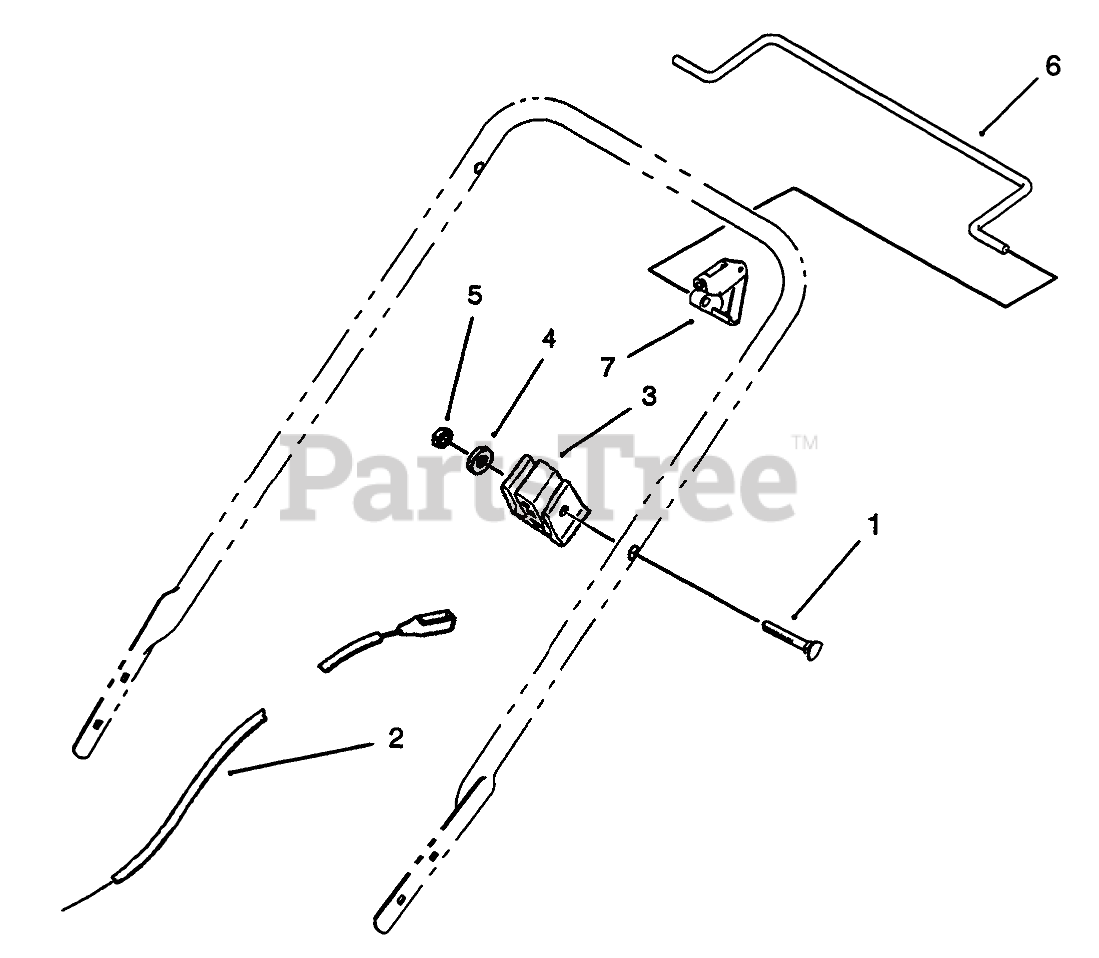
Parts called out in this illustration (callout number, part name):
1	SCREW-HANDLE
2	BRAKE CONTROL
3	SUPPORT-CABLE
4	WASHER-FLAT
5	NUT-LOCK, NI
6	Bar-Control
7	STOP-PIVOT
